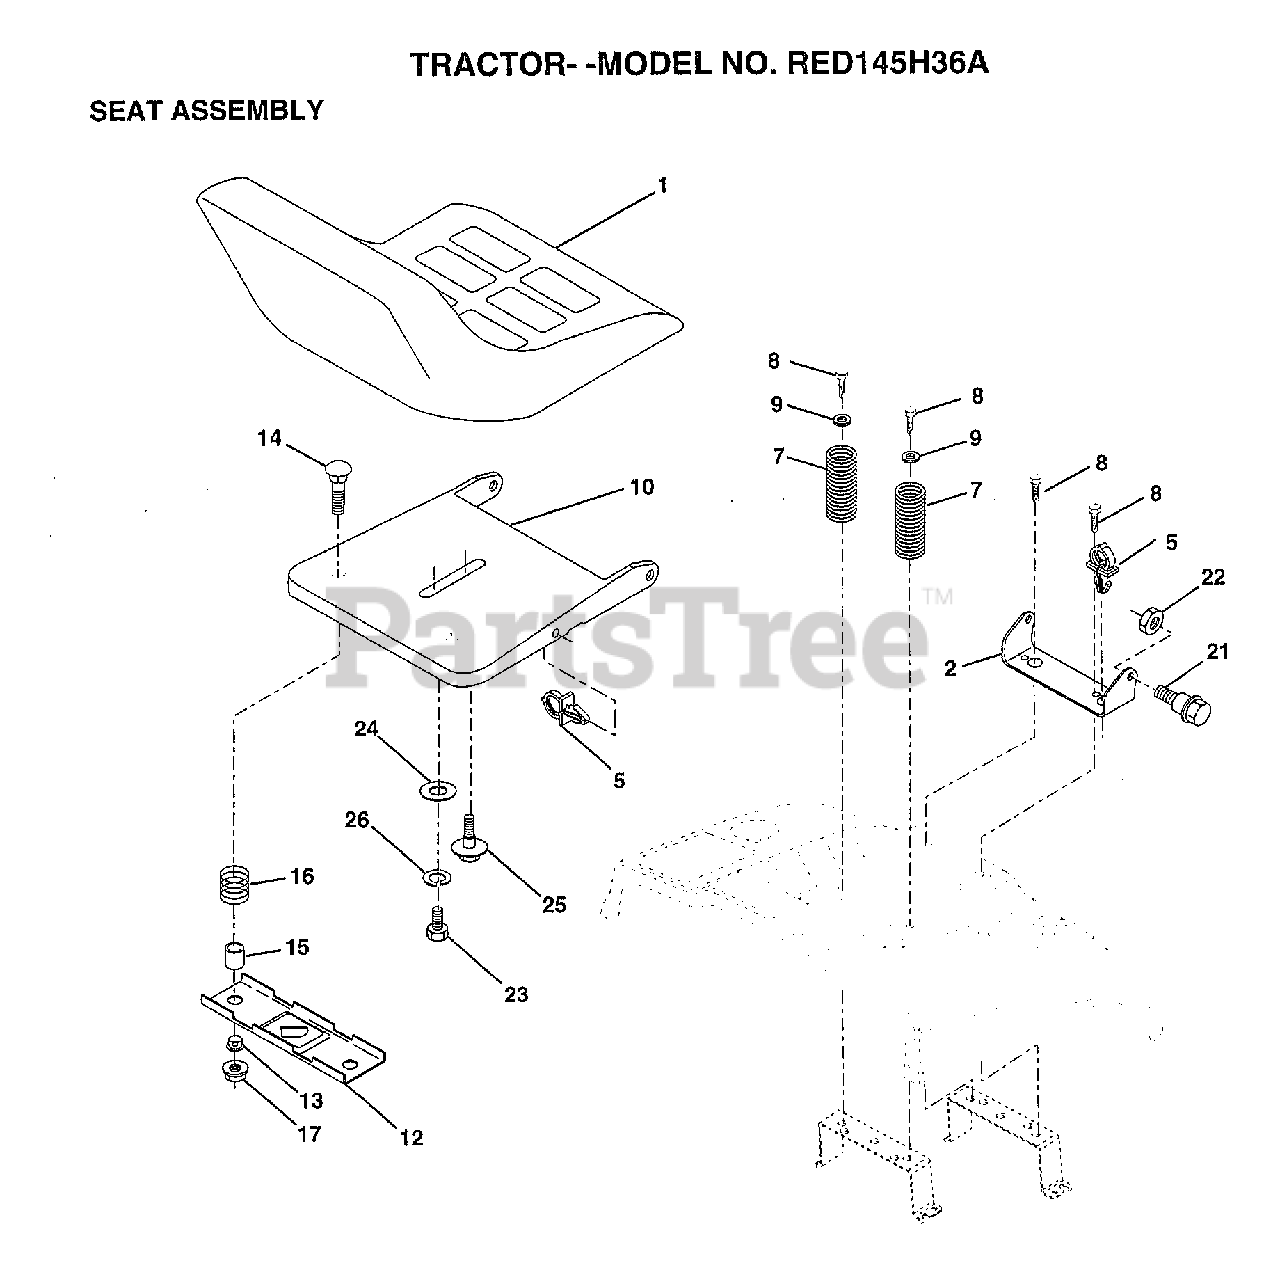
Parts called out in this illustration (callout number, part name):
2	BRACKET PVT SEAT
5	CLIP.PUSH-IN.HING
7	SPRING COMPRESSIO
8	SCREW GTV
9	WASHER
10	PAN-SEAT
12	BRKT SWITCH
13	BUSHING
14	BOLT-RD HD SQ NK
15	SPLIT SPACER
16	SPRING
21	"BOLT,SHOULDER"
22	NUT
23	BOLT
24	WASHER
25	"BOLT,SHOULDER"
26	LOCKWASHER
